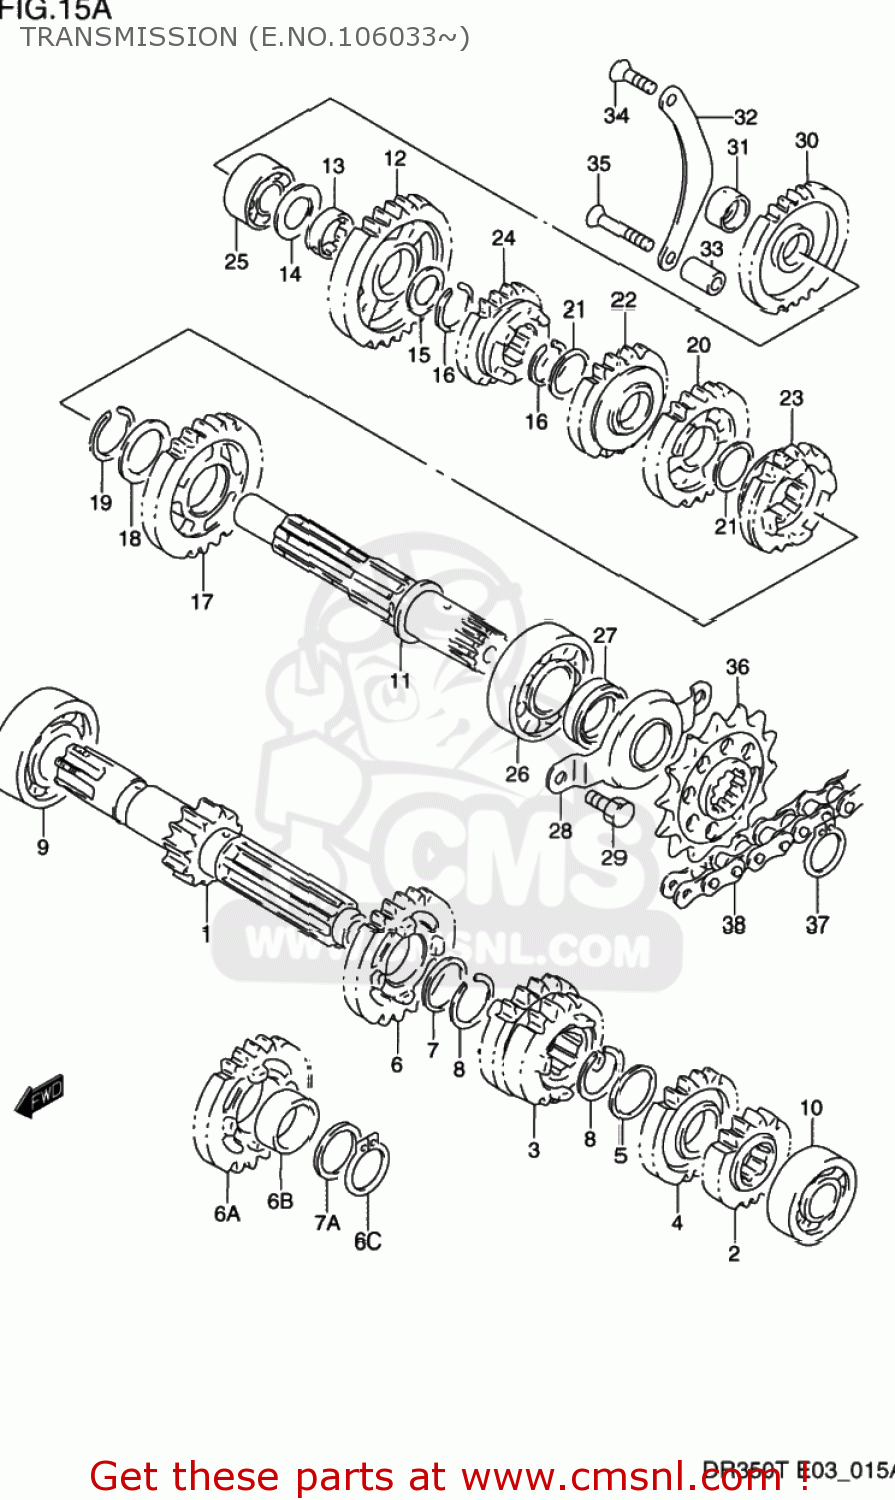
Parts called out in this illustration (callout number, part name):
1	SHAFT,COUNTER
2	GEAR,SECOND DRIVE (NT:15)
3	GEAR,3RD & 4TH DRIVE(NT:18/18)
4	GEAR,5TH DRIVE(NT:21)
5	WASHER
6	GEAR COMP,SIXTH DRIVE
6A	GEAR,6TH DRIVE(NT:23)
6B	BUSH(22X26X9)
6C	CIRCLIP
7	SHIM
7A	WASHER,THRUST
8	CIRCLIP
9	BEARING
10	BEARING
11	SHAFT,DRIVE
12	GEAR,1ST DRIVEN(NT:30)
13	BUSH,1ST DRIVEN GEAR
14	WASHER
15	WASHER,THRUST
16	CIRCLIP
17	GEAR,2ND DRIVEN(NT:26)
18	WASHER
19	CIRCLIP
20	GEAR,THIRD DRIVEN
21	SHIM
22	GEAR,4TH DRIVEN(NT:20)
23	GEAR,FIFTH DRIVEN (NT:20)
24	GEAR,SIXTH DRIVEN
25	BEARING(17X40X17.5)
26	BEARING(22X56X16)
27	SEAL,OIL(22X34X7)
28	RETAINER,DRIVE SHAFT OIL SEAL
29	BOLT
30	GEAR,KICK STARTER IDLE(NT:27)
31	BUSH,KICK STARTER IDLE GEAR
32	RETAINER,KICK IDLE GEAR
33	SPACER (6.5X12X21)
34	SCREW
35	SCREW
36	SPROCKET,ENGINE
37	CIRCLIP
38	CHAIN ASSEMBLY,DRIVE
